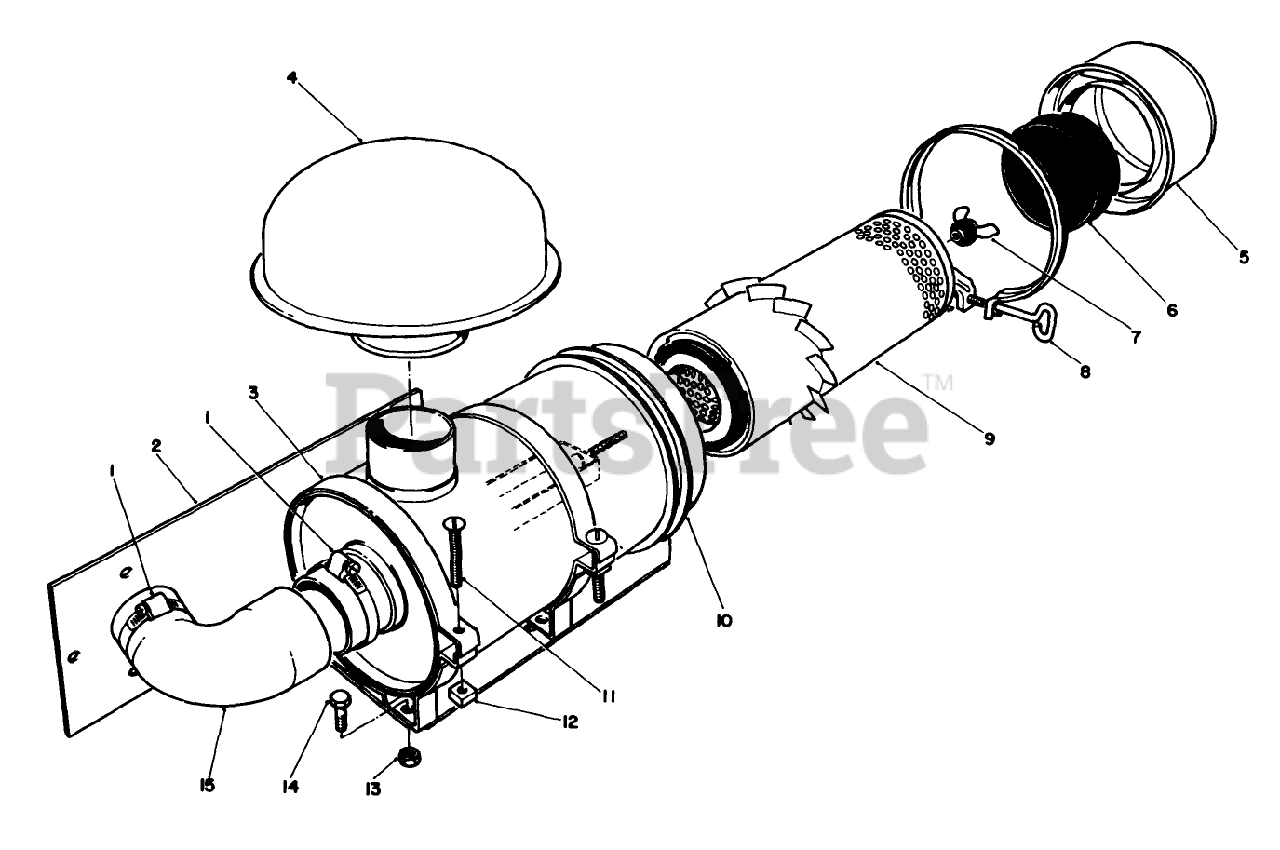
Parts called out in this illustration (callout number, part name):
1	CLAMP-HOSE
2	MTG BRACKET WA
3	MTG BAND ASM
4	HOOD-INLET, AIR
5	CUP ASM
6	BAFFLE
7	NUT ASM
8	CLAMP ASM
9	ELEMENT ASM
10	Body Assembly
11	SCREW
12	NUT-SQUARE
13	NUT-LOCK, NI
14	SCREW-HH
15	REMOTE AIR CLEANER HOSE
